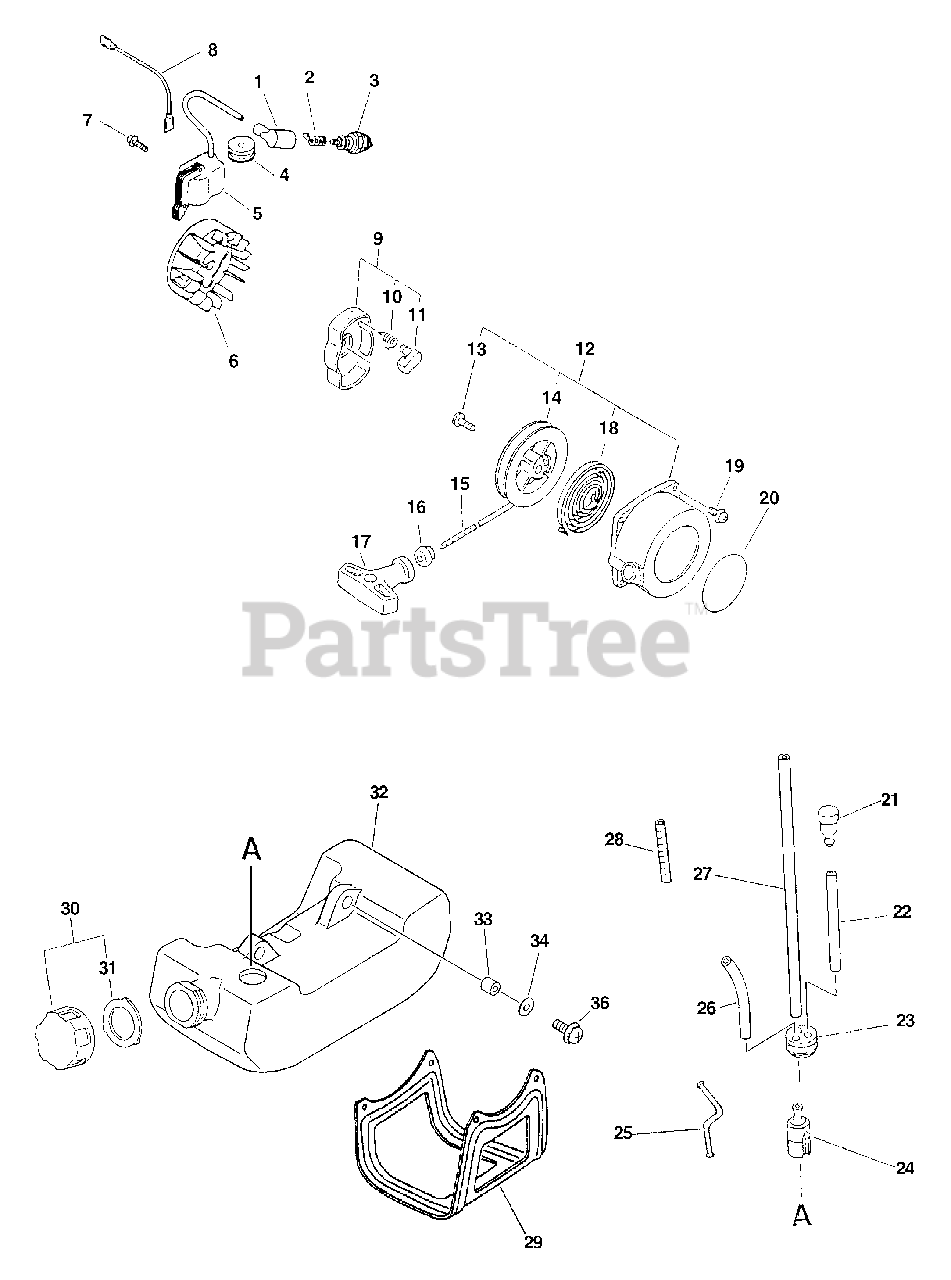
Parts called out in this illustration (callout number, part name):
1	CAP, SPARK PLUG
2	TERMINAL, SPARK PLUG
3	SPARK PLUG - BPM-7Y
3	SPARK PLUG - BPMR7A
5	COIL, IGNITION
6	FLYWHEEL
7	SCREW 4×22
8	LEAD
9	PAWL ASSY, STARTER
10	SPRING, RETURN
11	PAWL, STARTER - BLACK
12	STARTER ASSY
13	SCREW
14	REEL, ROPE
16	GUIDE, ROPE
17	GRIP, STARTER
18	SPRING, RECOIL
19	BOLT 4×16
20	LABEL, ECHO
21	VENT ASSY
22	PIPE, FUEL 3x-5x-70 BLACK
23	GROMMET, FUEL
24	FILTER, FUEL
25	CONNECTOR, PIPE
26	PIPE, FUEL RETURN 3×6×90 MM CLEAR
27	PIPE, FUEL 3x-5x-180
28	PIPE, FUEL 3×7×100 FLEXIBLE
29	GUARD, FUEL TANK
30	CAP ASSY, FUEL
31	GASKET, FUEL CAP
32	TANK, FUEL
33	SPACER 6.2×7.8×6
34	WASHER 5.5×12×0.8
35	SCREW 5×16
